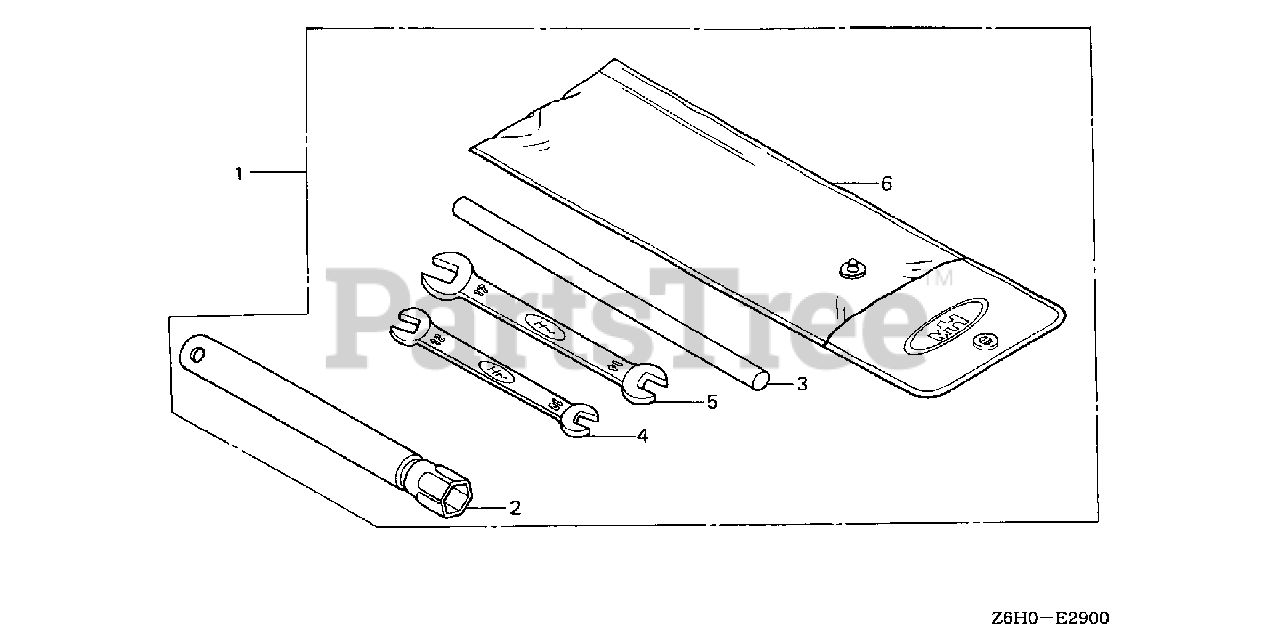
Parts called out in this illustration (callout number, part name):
1	TOOL KIT
2	WRENCH, SPARK PLUG
3	HANDLE, BOX WRENCH
4	SPANNER (10X12)
5	SPANNER (14X17)
6	BAG, TOOL (230MM)
